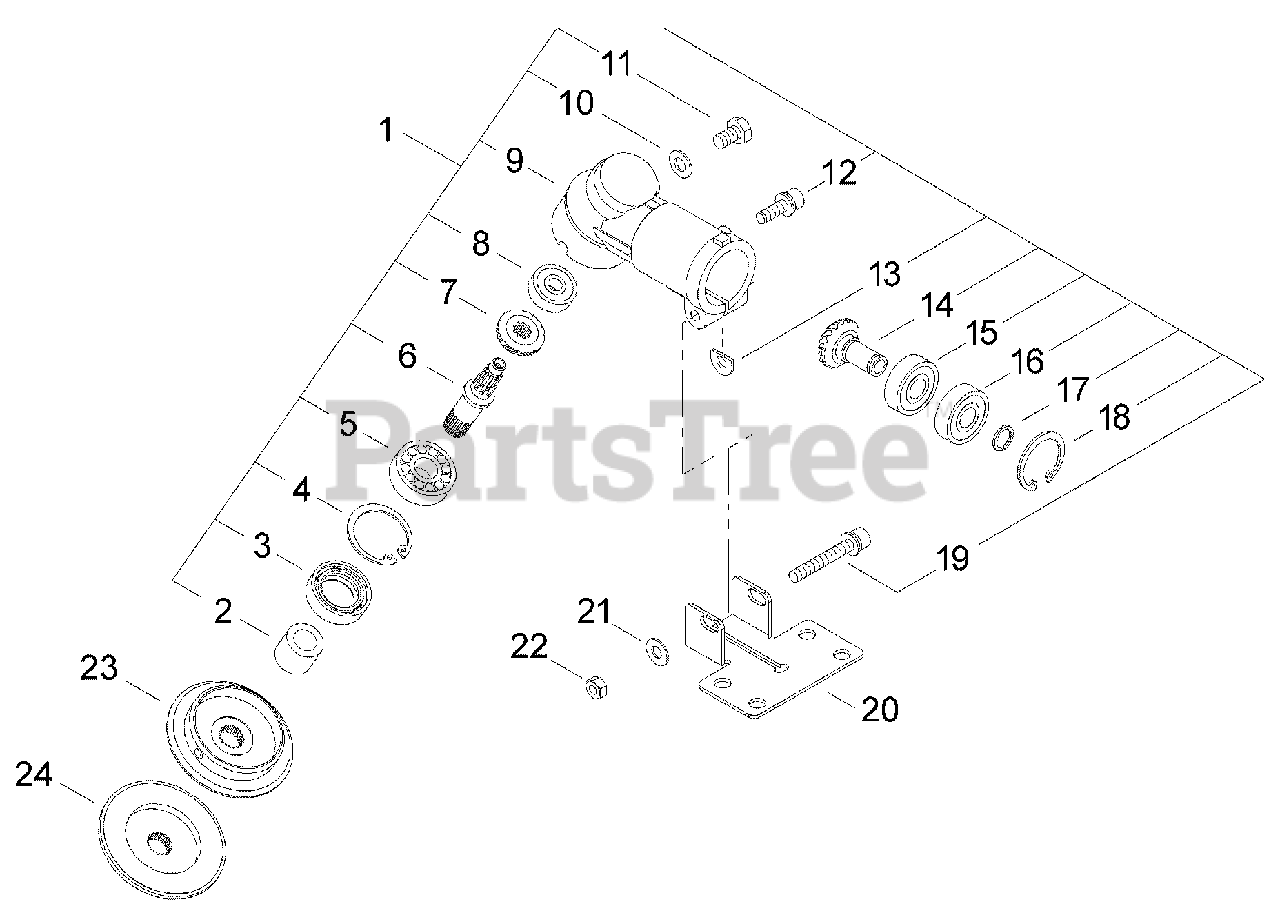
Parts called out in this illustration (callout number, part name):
1	GEAR CASE ASSY
2	SPACER
3	SEAL, OIL
4	RING, SNAP Ø32
5	BEARING, BALL 6201
6	SHAFT, GEAR
7	GEAR, BEVEL
8	BEARING, BALL
9	CASE, GEAR
10	WASHER
11	BOLT M6×10
12	BOLT M5×16
13	D-WASHER
14	GEAR, PINION
15	BEARING, BALL 6901
16	BEARING, BALL 6901ZZ
17	RING, SNAP Ø12
18	RING, SNAP Ø24
19	BOLT M6×40
20	PLATE, SHIELD MOUNTING
21	WASHER 6.5×13×1
22	NUT, HEX M6
23	PLATE, ADAPTOR - UPPER
24	PLATE, ADAPTOR - LOWER
